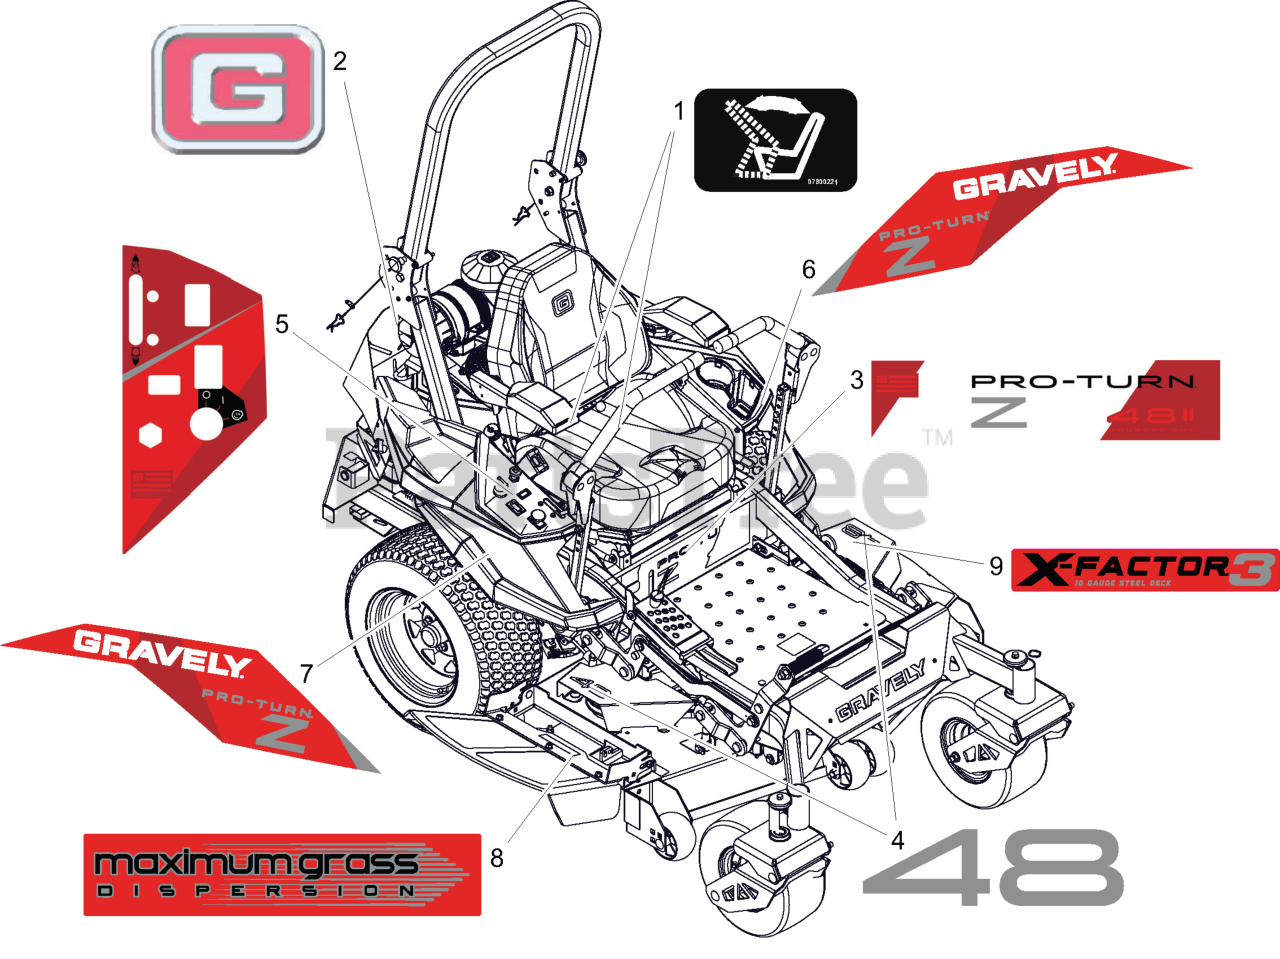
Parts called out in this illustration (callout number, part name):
1	DECAL - SEAT RELEASE
2	DECAL, GRAVELY BRAND
3	DECAL, PTZ - 48
4	DECAL, DECK - 48
5	DECAL, CONTROL PANEL
6	DECAL, FENDER LH - PTZ
7	DECAL, FENDER RH - PTZ
8	DECAL, DECK - MAX GRASS
9	DECAL, X-FACTOR 3
